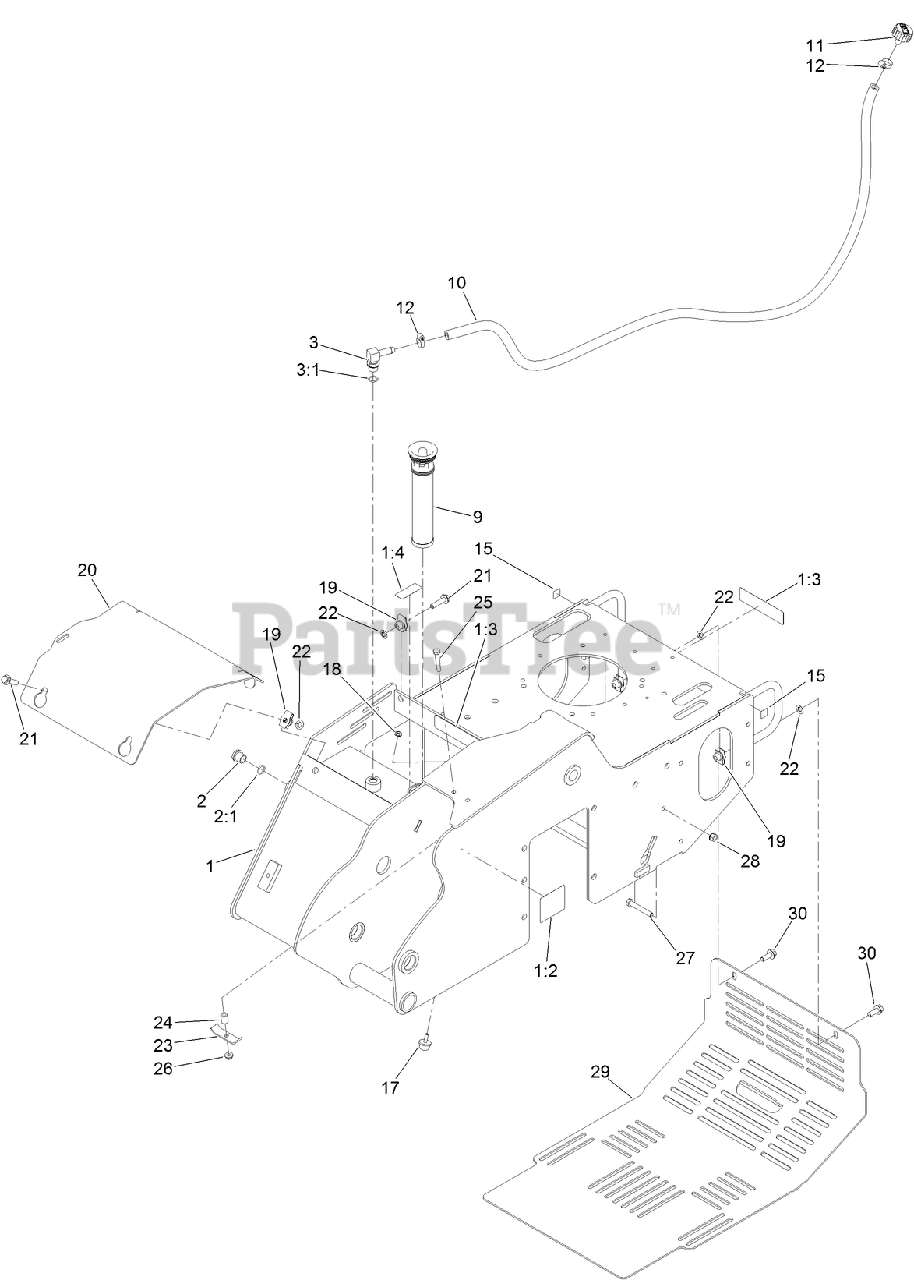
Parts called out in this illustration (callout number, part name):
1	MAIN FRAME ASM
1:2	DECAL-WARNING
1:3	DECAL-DANGER
1:4	DECAL-OIL, HYD
2	SIGHT GLASS ASM
2:1	O-RING
3	FITTING-ELBOW, 90
3:1	O-RING
9	IN-TANK FILTER ASM
10	HOSE-BREATHER
11	BREATHER
12	CLAMP-HOSE
15	DECAL-POINT, LIFT
17	BUMPER
18	NUT-HF
19	NUT-TINNERMAN
20	PLATE-COVER, FRONT
21	SCREW-HHF
22	NUT-PUSH
23	BRACKET-CLAMP
24	SPACER
25	SCREW-HH
26	NUT-HF
27	SCREW-HH
28	NUT-FLANGE
29	COVER-REAR
30	SCREW-HHF
